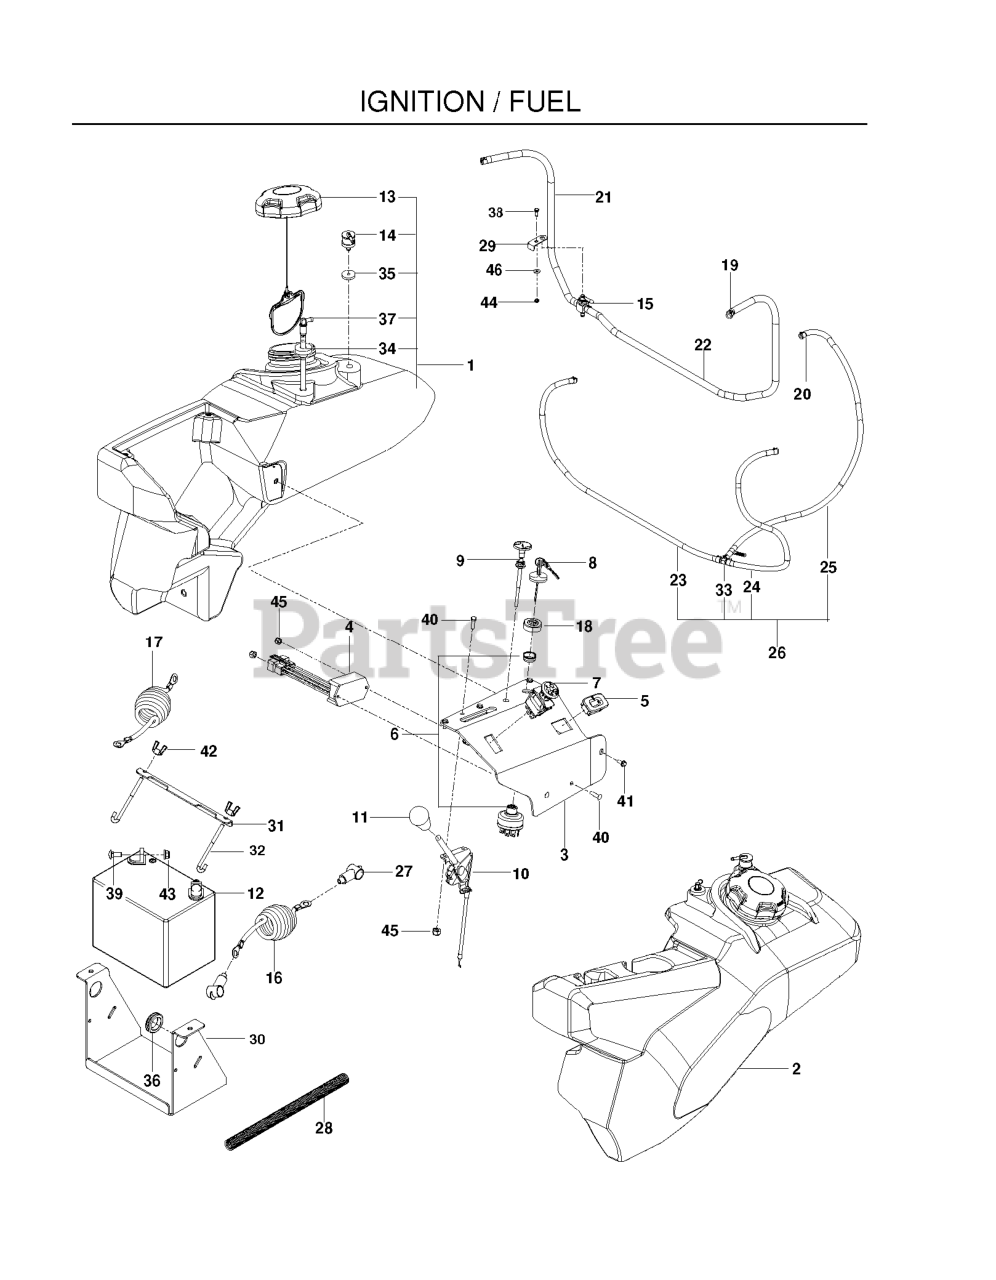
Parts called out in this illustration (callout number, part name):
1	RT FUEL TANK ASM EPA
2	LT FUEL TANK ASM EPA
3	PANEL.CONTROL.GAS.GRAY
4	TIMER, SEAT
5	HOUR METER
6	SWITCH, IGNITION, INDAK
7	SWITCH, PTO 10 AMP
8	KEY, IGNITION
9	CABLE, CHOKE, 48"
10	CABLE, THROTTLE, 46"
11	KNOB - SHIFT
12	BATTERY, 12 V 330 AMP
13	CAP, FUEL
14	VALVE.FUEL.CHECK
15	FUEL VALVE
16	CABLE, POSITIVE, 55"
17	CABLE, NEG, 55"
18	CAP IGNITION NUT
19	HOSE CLAMP
20	CLAMP, HOSE
21	LINE, FUEL, 22"
22	LINE, FUEL, 38"
23	HOSE, 3/16" VAPOR, 21"
24	HOSE, VAPOR 3/16 X 39"
25	HOSE, VAPOR 3/16 X 30"
26	ASSEMBLY, VAPOR LINE
28	LOOM, SPLIT, CONVOLUTED
29	BRACKET,FUEL VALVE, BLACK
30	BRACKET, BATTERY, BLK
31	BRACKET, BATTERY MOUNT
32	HOOK, "J"
33	TEE, FUEL LINE 3/16"
34	RUBBER GROMMET
35	GROMMET, CHECK VALVE
36	RUBBER GROMMET
37	FITTING, FUEL
38	HCS 1/4C X 3/4 HCS
39	BOLT 5/16C X 3/4" CARRIAGE
40	SCR #10-24 X .75 SKT HD BLK
41	SCR #10-24 X 3/8 SKT HD BLK OX
42	WING NUT 1/4
43	5/16-18 NYLOC FLANGE NUT
44	JAM NUT 1/4C (2 2 PW01)
45	NUT 10-24 NYLOC
46	WASHER 1/4 FLAT
